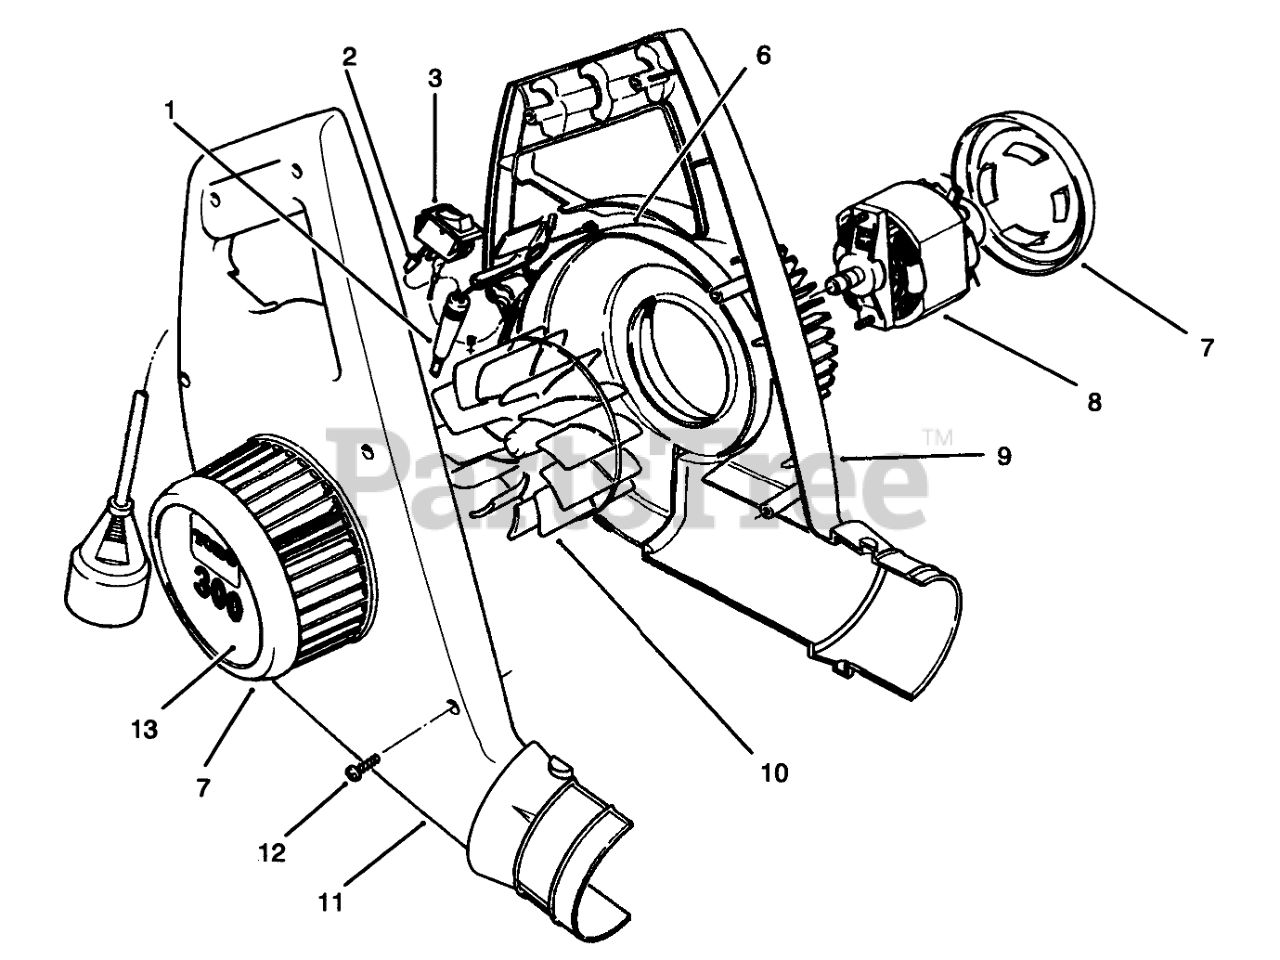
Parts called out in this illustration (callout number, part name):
1	POWER SUPPLY CORD
2	CONNECTOR-NUT, WIRE
3	ROCKER SWITCH W/LETTERS
6	MOTOR COVER - 300 BLO
7	INTAKE COVER-300 BLO
8	MOTOR, 300 MINI-BLOWER
9	HOUSING LH - 300 BLOWER
10	IMPELLER-MINI BLOWER
11	HOUSING RH - 300 BLOWER
12	Screw
13	COVER - LABEL
